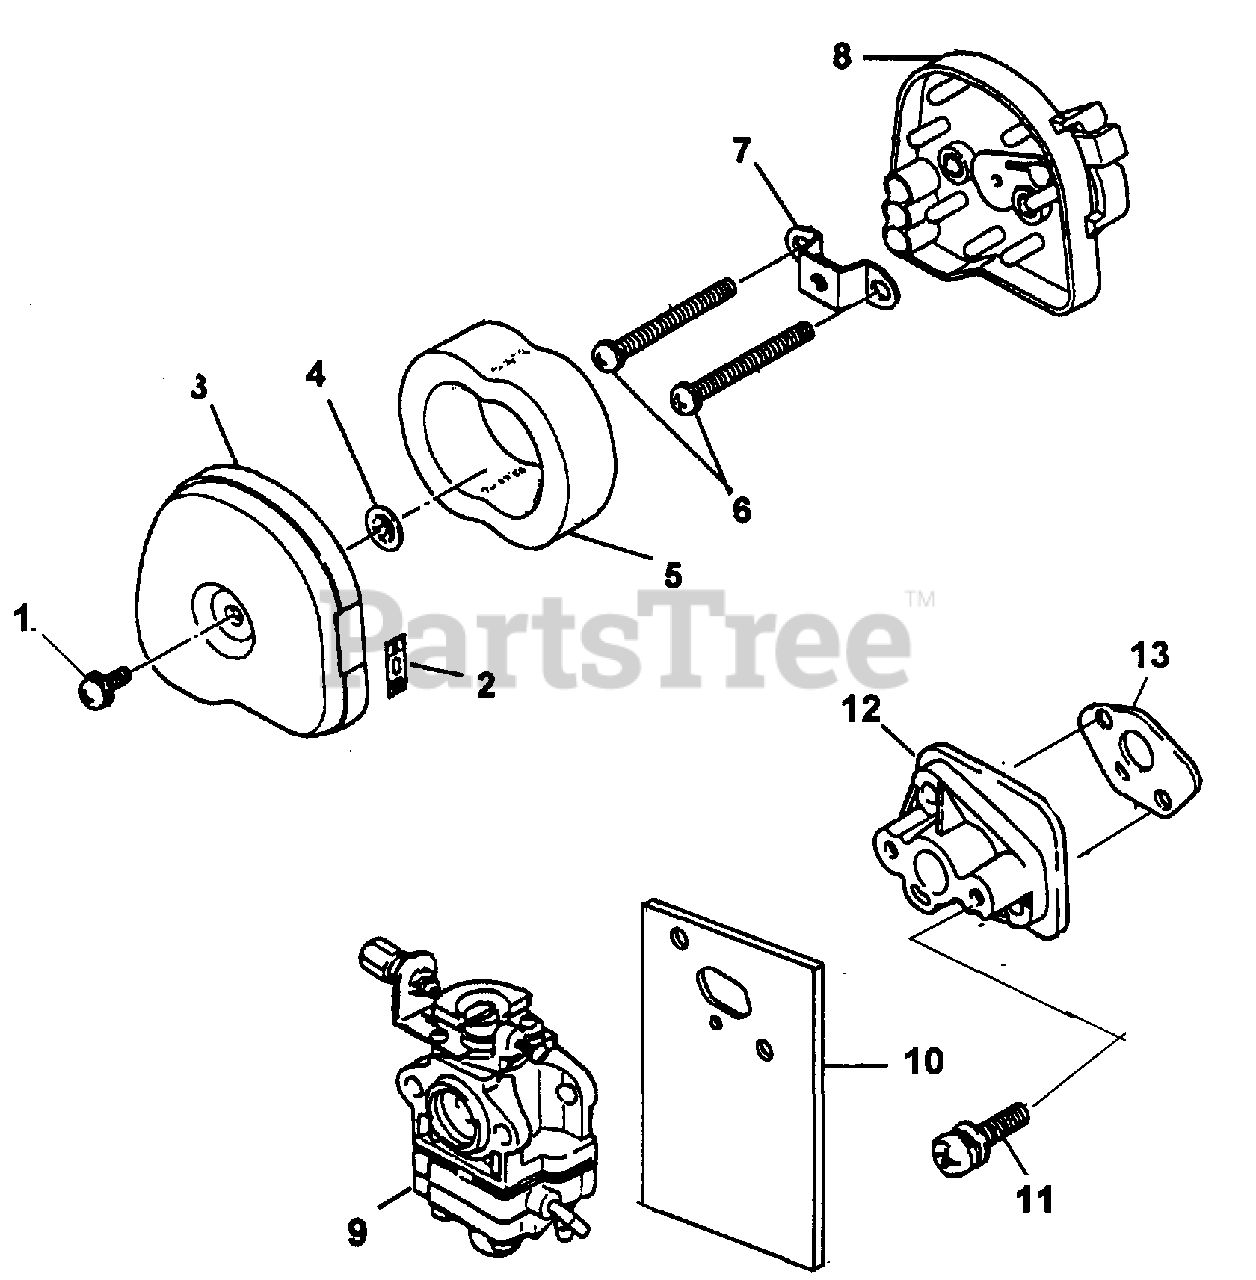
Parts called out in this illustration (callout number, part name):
1	SCREW & WASHER
2	LABEL, NAME
3	COVER, AIR CLEANER
5	ELEMENT AIR CLEANER
6	SCREW & WASHER
7	BRACKET
8	CASE, CLEANER
9	CARBURETOR ASSY
10	GASKET, CARBURETOR
11	SCREW & WASHER
12	INSULATOR
13	GASKET INSULATOR
